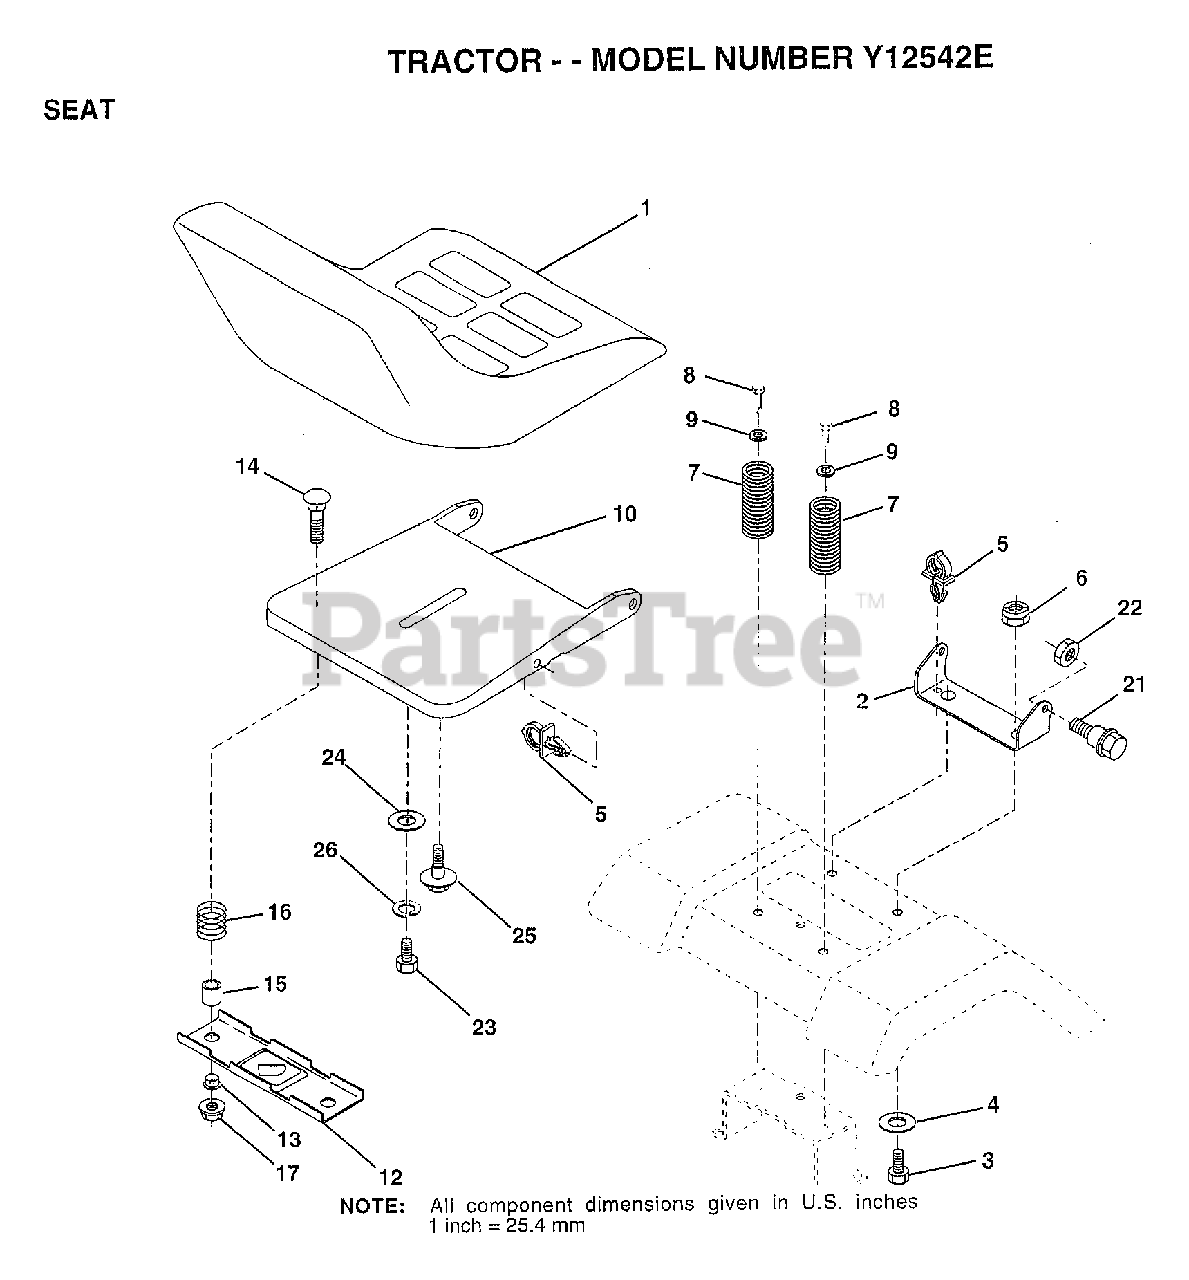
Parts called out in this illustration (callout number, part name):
2	BRACKET PVT SEAT
3	BOLT
4	WASHER PM
5	CLIP.PUSH-IN.HING
6	NUT
7	SPRING COMPRESSIO
8	SCREW GTV
9	WASHER
10	PAN-SEAT
12	BRKT SWITCH
13	BUSHING
15	SPLIT SPACER
16	SPRING
21	"BOLT,SHOULDER"
22	NUT
23	BOLT
24	WASHER
25	"BOLT,SHOULDER"
26	LOCKWASHER
